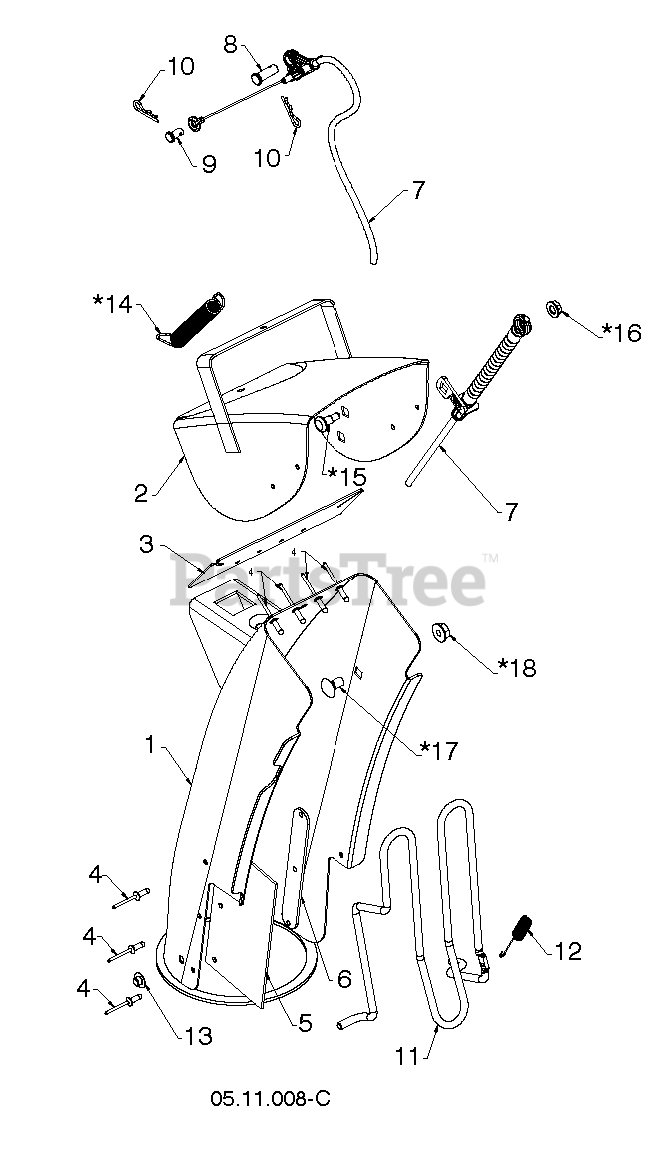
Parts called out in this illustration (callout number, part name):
1	CHUTE.WELDMENT.SNOW.ORANGE
2	DEFLECTOR.WELDMENT.PNT.ORANGE
3	SEAL.DEFLECTOR
4	RIVET BLIND
5	SHIELD.SNOW.CHUTE
6	STRAP.SHEILD.RETAINER
7	CABLE CONTROL.CHUTE.DEFL.BOWDE
8	PIN CLEVIS 5/16X.875
9	PIN CLEVIS .25 X .31
10	HAIRPIN.SOFT.ZINC.059X1.125
11	ROD.GUARD.CHUTE (2 2)
12	SPRING.CHUTE.GUARD
13	NUT
